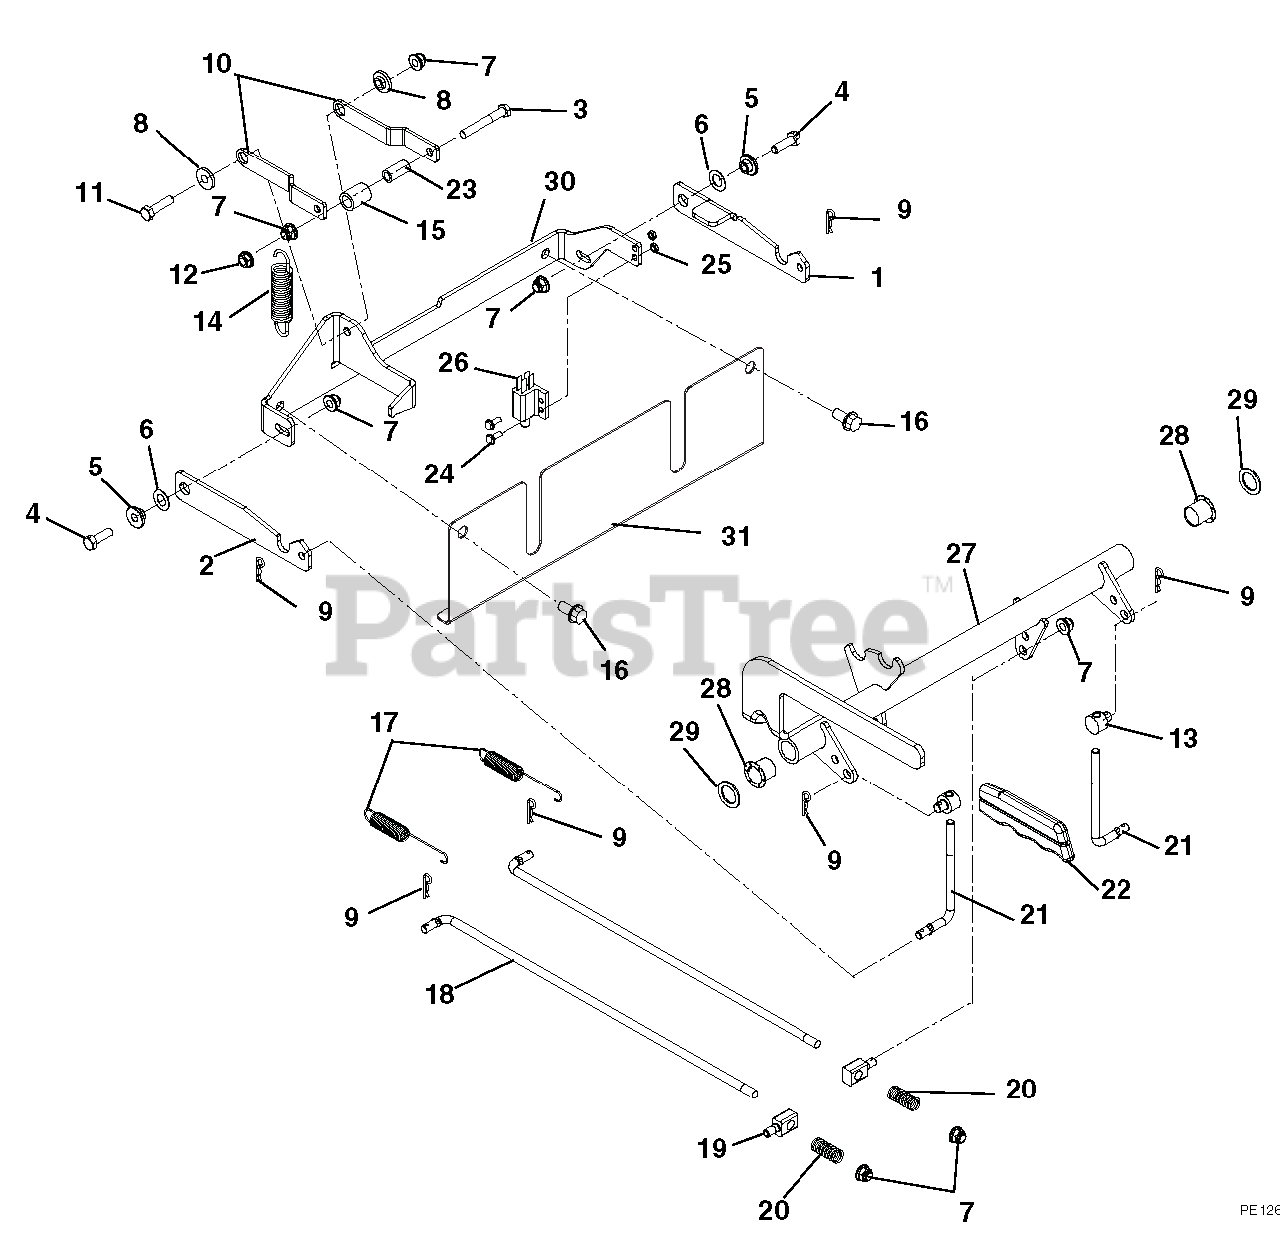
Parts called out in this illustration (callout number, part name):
1	LINK, BRAKE INTERLOCK
2	INTERLOCK, BRAKE
3	@BLT-HEX .31-18X2.25 GR5 YWZC
4	@BLT-HEX .31-18X1.00 GR5 YWZC
5	BSHG-FLG .32X.500X.344X.880
6	WSHR-FL-STL .505X.875X.024 YWZ
7	@NUT-LK-NYL-FLG .31-18 YWZC
8	BSHG, FLG .325X.499X.26X.88
9	PIN-HAIR INT .08X.18X1.18 YWZC
10	ARM, BRAKE CAM
11	@BLT-HEX .31-18X1.25 GR5 YWZC
12	@NUT-LK-TOP-FLG .31-18 YWZC
13	TRUNNION, BRAKE .31-18 UNC
14	SG-TENS .105X.812X3.88 WLD 15
15	ROLLER, CAM LOCK
16	@SCR-TAP .38-16X.75 HWH TR YWZ
17	SG-TENS .056X.60X4.40
18	ROD, PARK BRAKE
19	PIN, PIVOT/TRUNNION
20	SPRING, COMPRESSION
21	LINK, INTERLOCK BRAKE
22	GRIP, PARKING BRAKE (YELLOW)
23	BSHG, SPCR .330X.500X1.01 PM
24	@SCR-MCH 10-24X.50 HWH YWZC
25	@NUT-LK-NYL 10-24 W/INSRT YWZC
26	SWITCH- DOUBLE POLE N.O./N.O.
27	SHAFT, BRAKE
28	BUSHING, IGLIDE CLIP
29	WSHR-FL-STL.754X1.125X.062YWZC
30	BRKT, BRAKE MTG
31	BRKT, LOWER FINGER GUARD - XL
